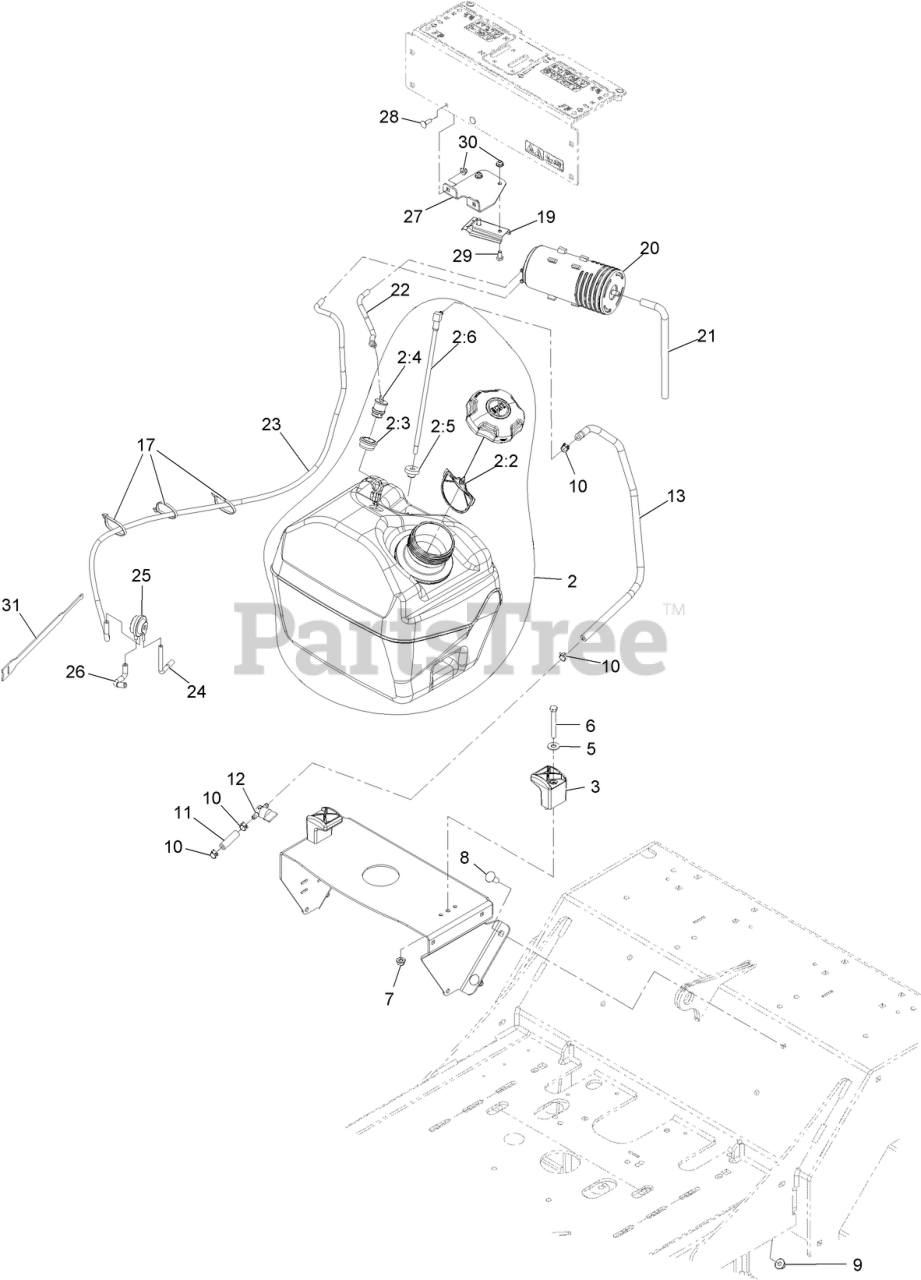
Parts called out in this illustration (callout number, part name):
2	ASM-FUEL TANK, 5 GAL, UNLABEL
2:2	CAP-FUEL, RATCHETING
2:3	GROMMET
2:4	VALVE-VENT, FUEL
2:5	BUSHING
2:6	FITTING, FUEL W/LINE AND SCREEN
3	CLAMP-TANK
5	WASHER-FLAT
6	SCREW-HH
7	NUT-HF, NI
8	SCREW-CARR
9	NUT-HF, NI
10	CLAMP-HOSE
11	HOSE-FUEL
12	VALVE-FUEL
13	HOSE-LINE, GAS
17	TIE-CABLE
19	BRACKET-CANISTER, CARBON
20	CANISTER-CARBON, 800CC
21	HOSE-VENT, CANISTER
22	HOSE-EMISSIONS
23	HOSE-VENT, FORMED
24	HOSE-VENT, FORMED
25	VALVE-CONTROL, VACUUM
26	HOSE-VENT, FORMED
27	BRACKET-MOUNTING, CANISTE
28	BOLT-CARR
29	SCREW-HH
31	STRAP-VELCRO, CABLE TIE
